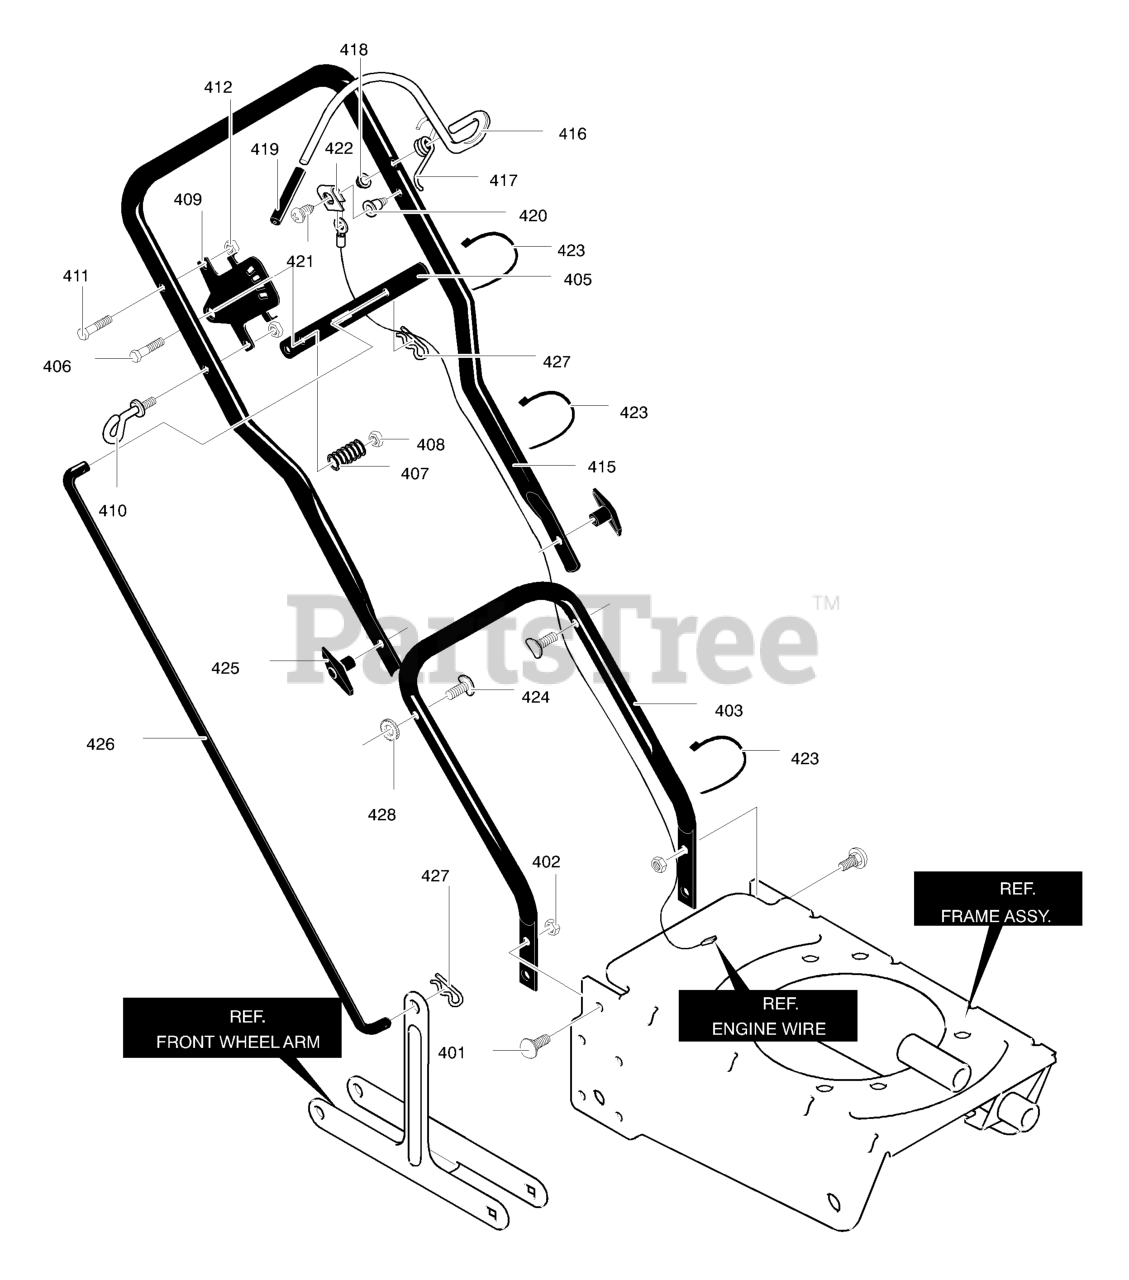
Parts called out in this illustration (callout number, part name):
401	Bolt, 5/16-18x.75
402	Nut, 5/16-18
403	Lower Handle
405	Handle, Depth
407	Spring, Compression
408	Nut, 5/16-18
409	Brkt, Adj. Quadrant
410	Rope Guide
411	Screw, 1/4-20x1.25
412	Nut, 1/4-20
415	Upper Handle
416	Bail, Operator Control
417	Torsion Spring
418	Nut, Push On
419	Cap, Operator Control
420	Insulator, Oper Control
421	Screw, #6x.50
422	Clip, Grounding
423	Cable Tie
424	Bolt, 5/16-18x.75
425	Wing Knob 5/16-18
426	Rod, Control
427	Hair Pin
428	Washer, Exlk.
